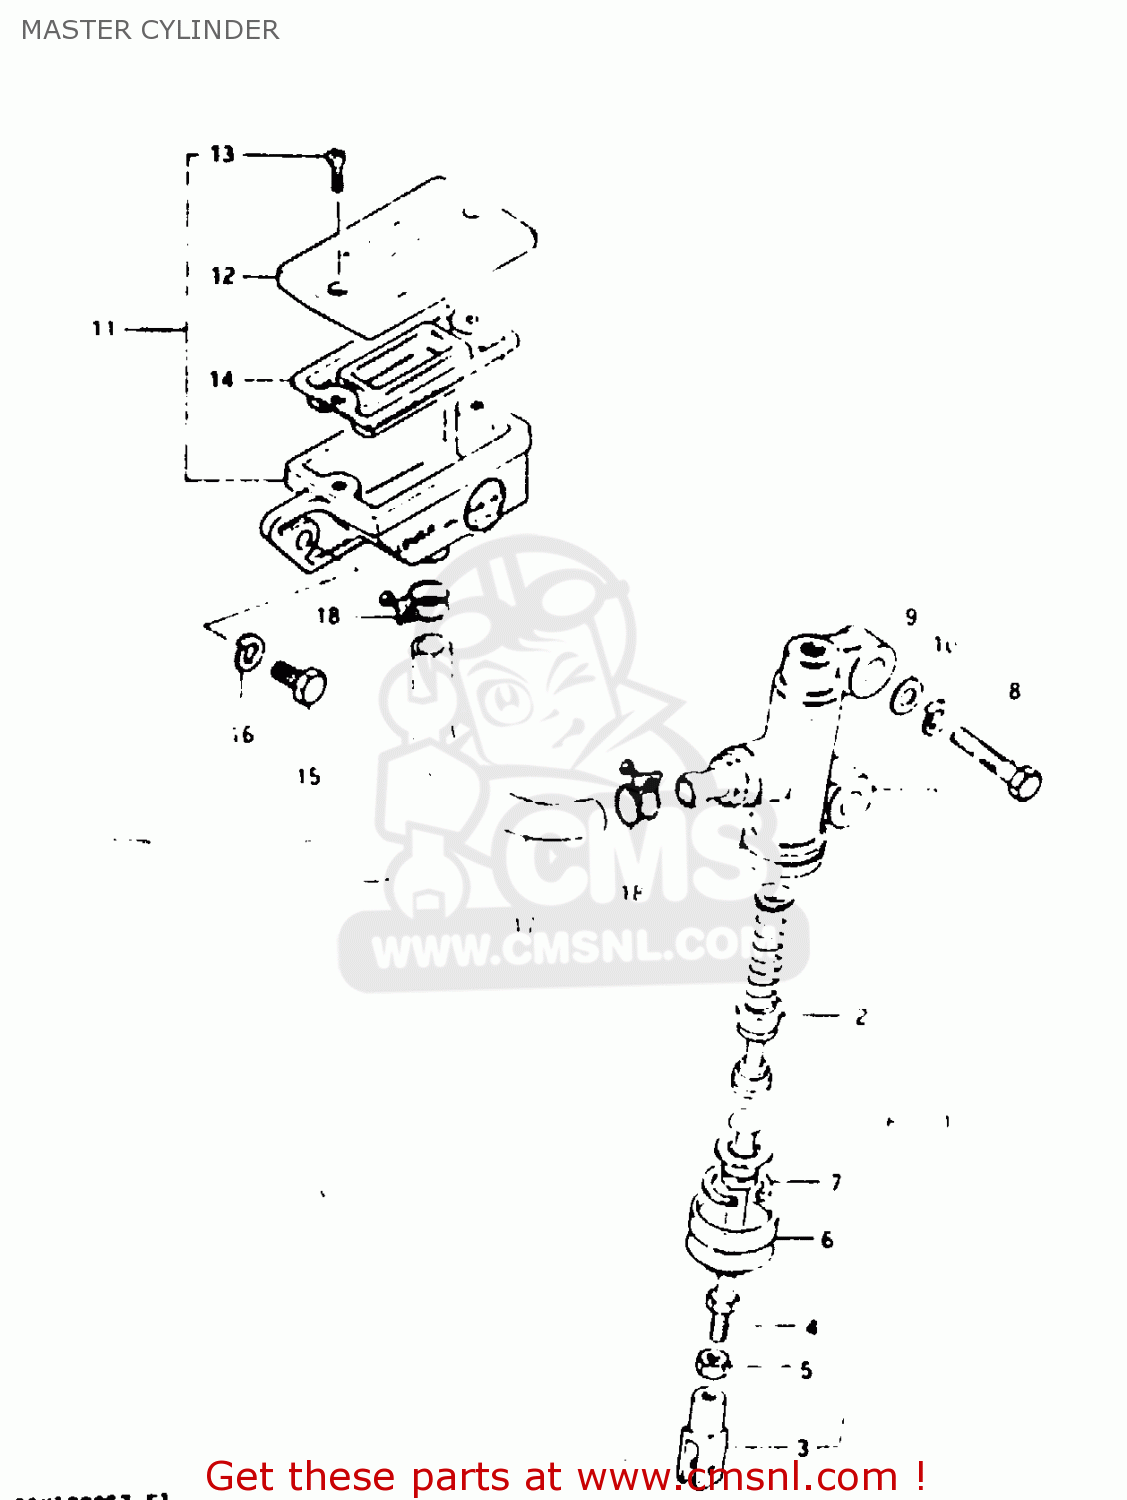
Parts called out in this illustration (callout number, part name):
1	CYLINDER ASSEMBLY,REAR MASTER
2	PISTON/CUP SET
3	YOKE
4	LOD,PUSH
5	NUT,MASTER CYLINDER
6	BOOT
7	CIRCLIP
8	BOLT (8X30)
9	WASHER
10	LOCK WASHER
11	RESERVOIR TANK ASSY
12	CAP
13	SCREW
14	15
15	BOLT, UPPER
16	LOCK WASHER
17	HOSE,RESERVOIR TANK
18	CLAMP
